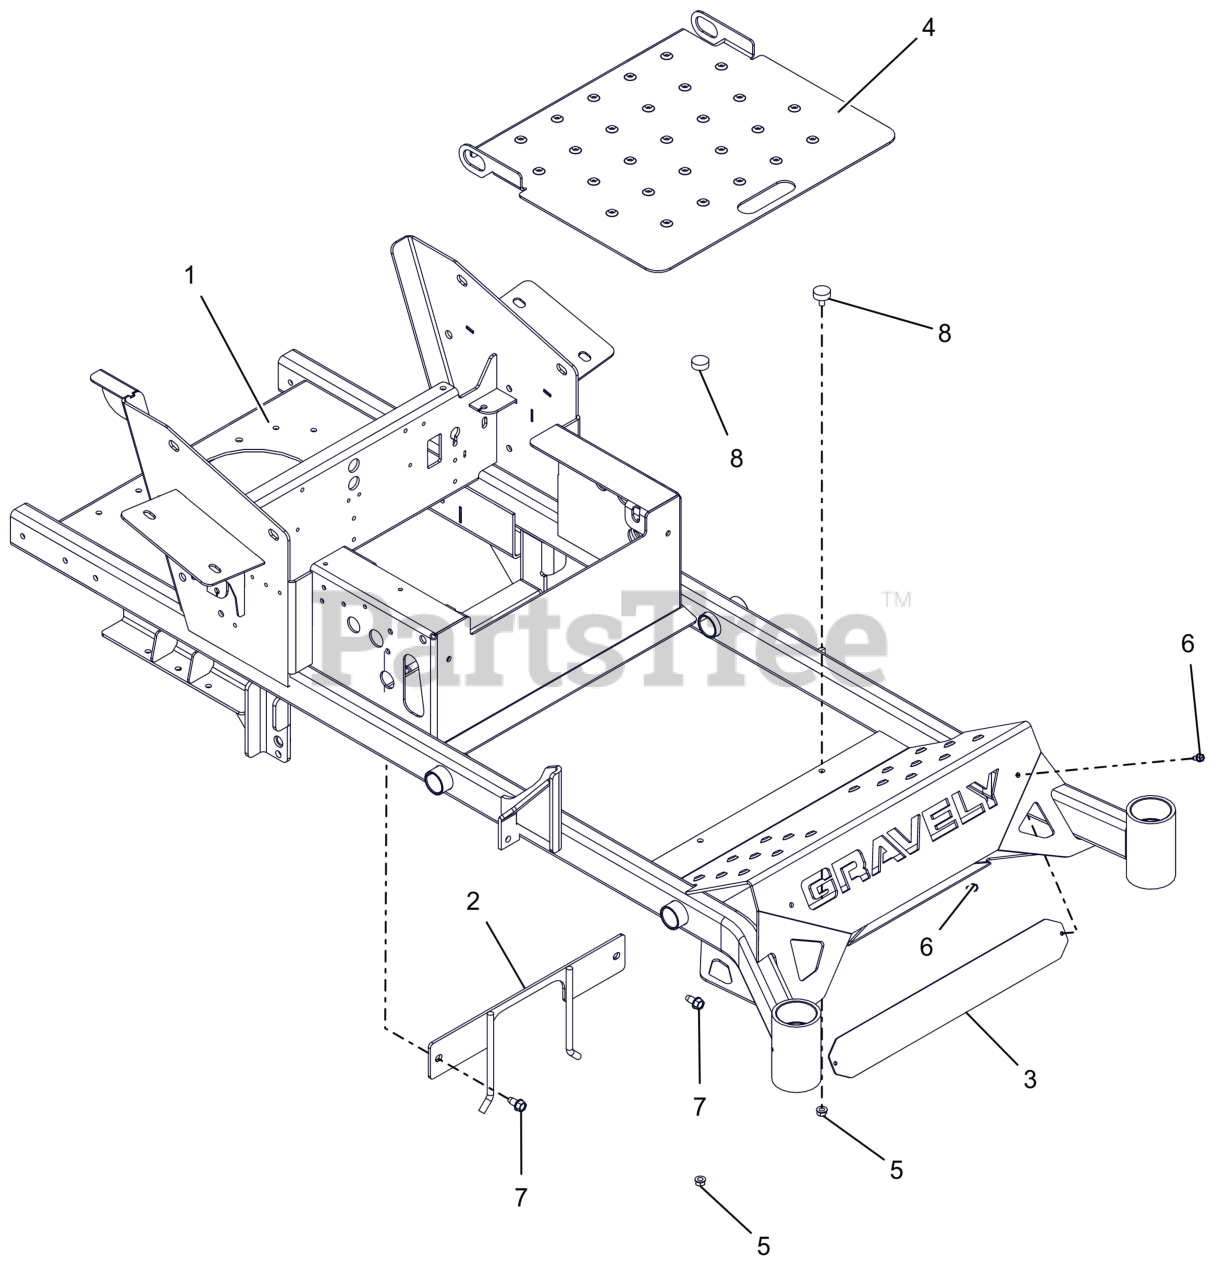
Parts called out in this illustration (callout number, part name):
1	PT/100 48-52 FRM W/SAFETY DECL
2	PTO BELT FINGER WLDMT - BLK
3	BUMPER LOGO BACKING PLATE -BLK
4	PT/100 FOOT PLT W/SAFETY DECAL
5	NUT,SPNLK-FLG .31-18 G5 ZCC
6	SCR-TAP .25-20X.50 HWH ZCC
7	SCR,TAP .375-16X.75 HWH TR ZCC
8	BUMPER, RUBBER
